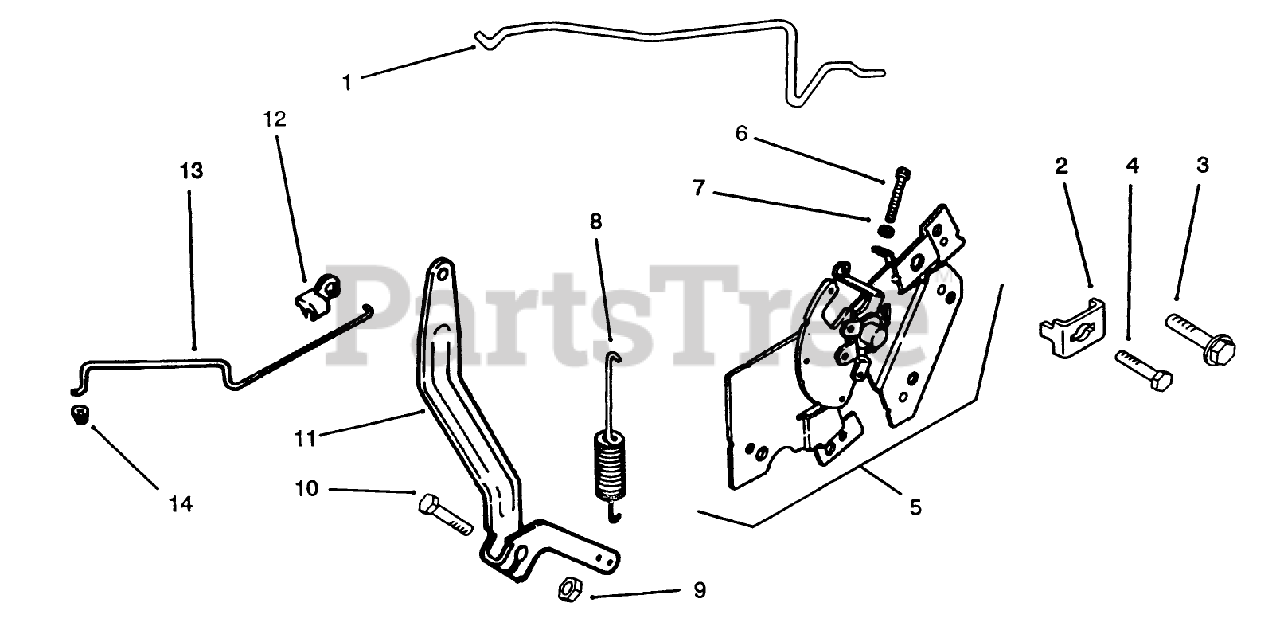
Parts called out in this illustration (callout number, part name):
1	Linkage-Choke (Only On: 72042,72043,72062,72063)
4	Screw M5x0.8x16 (Only On: 72042, 72063, 72062, 72043)
5	Control-ASM INC 6-7 (Only On: 72042, 72063, 72062, 72043)
6	Screw-HHF M4x0.7x28 (Only On: 72042, 72063, 72062, 72043)
7	Nut
8	Spring-Governor (Only On: 72042, 72063, 72062, 72043)
11	Lever-Governor (Only On: 72042, 72063, 72062, 72043)
12	Bushing-Linkage
13	Linkage-Throttle (Only On: 72042, 72063, 72062, 72043)
14	Bushing
